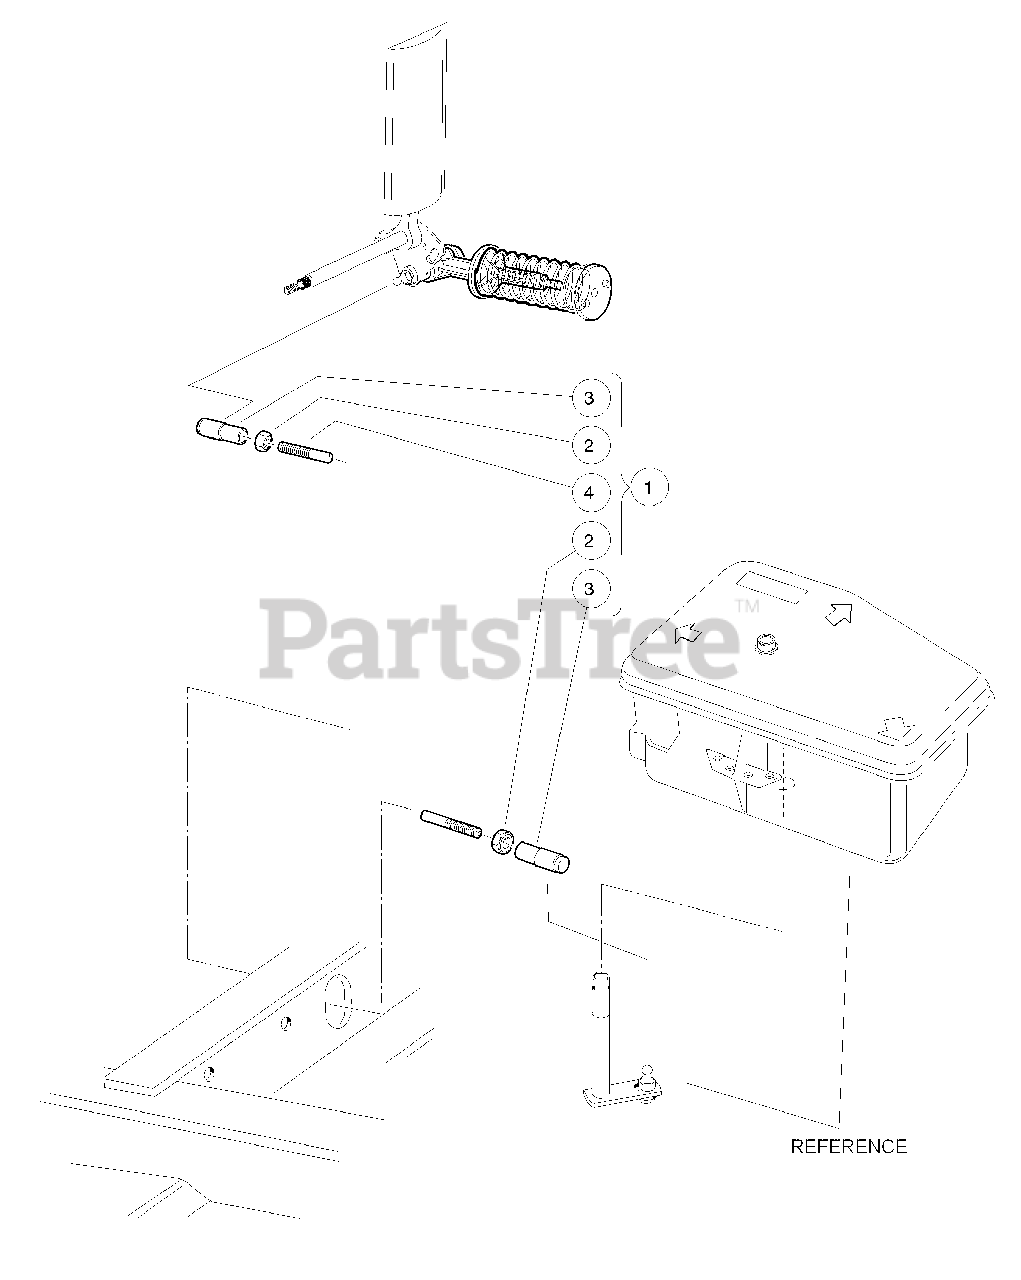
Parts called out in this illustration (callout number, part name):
1	Rod, Accelerator
2	Nut, 1/4-28 Hex Jam
3	Joint, Ball
4	Accelerator Rod
